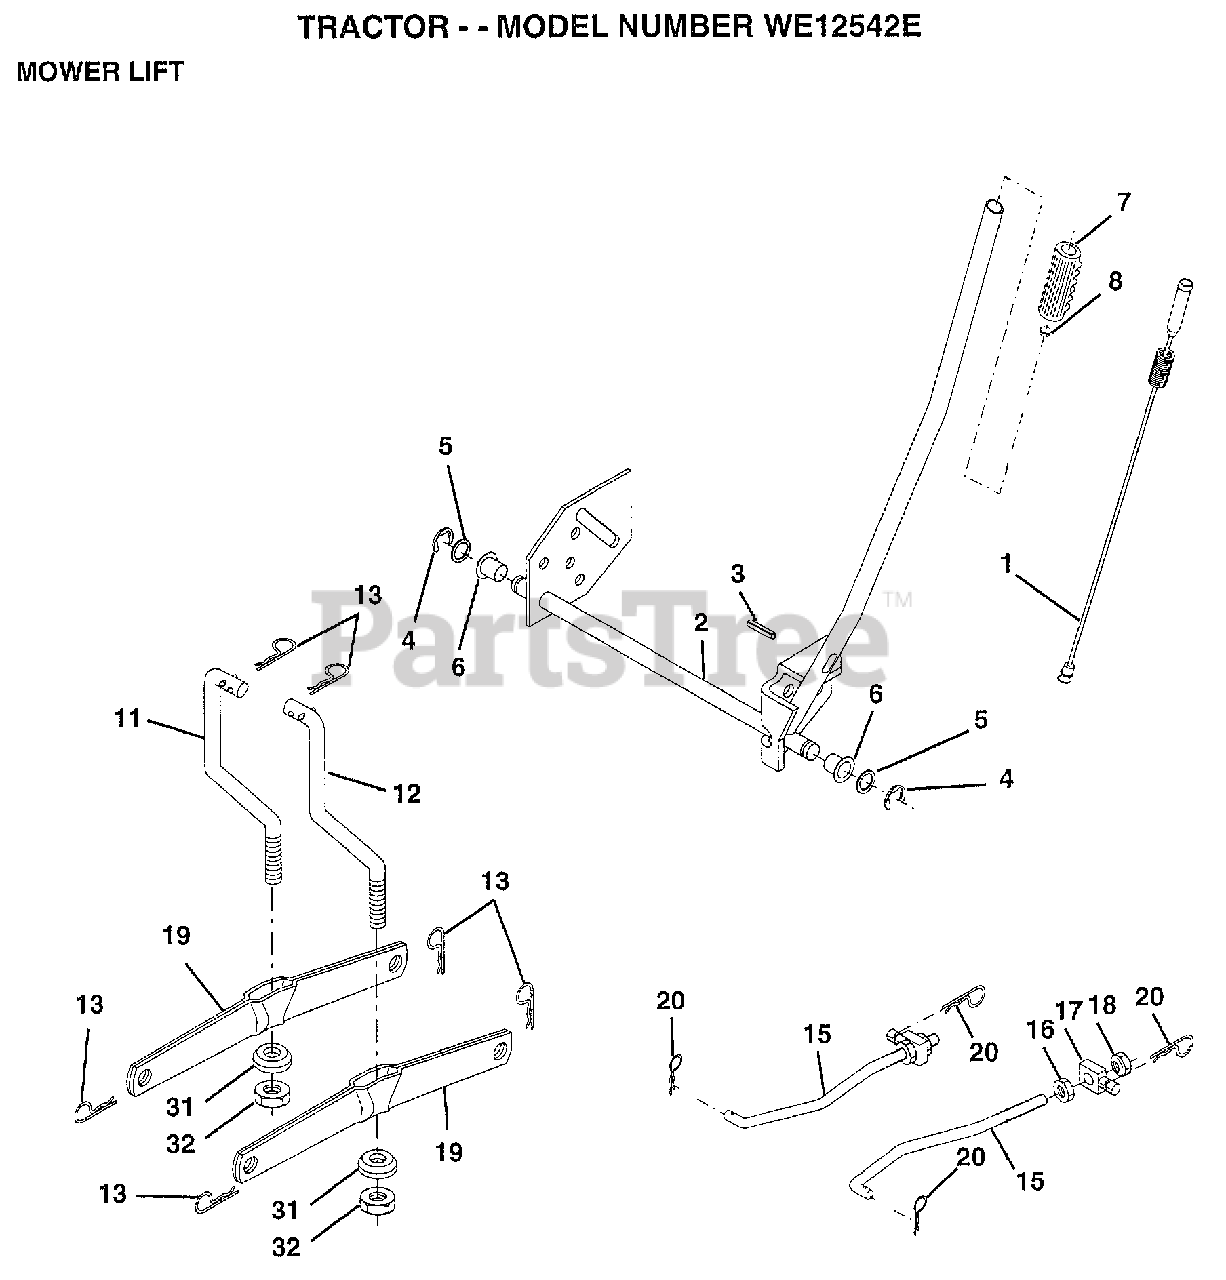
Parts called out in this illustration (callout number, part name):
1	WIRE ASM W.SPRING
2	"SHAFT ASM LIFT,RH"
3	PIN-GROOVE LT
5	WASHER
6	NYLON BEARING
7	GRIP
15	LINK.FRONT
16	NUT
17	TRUNION
18	NUT LTV
19	ARM SUSP REAR
20	RETAINER SPRING
31	BEARING PVT LH
32	NUT.CROWNLOCK.3/8
